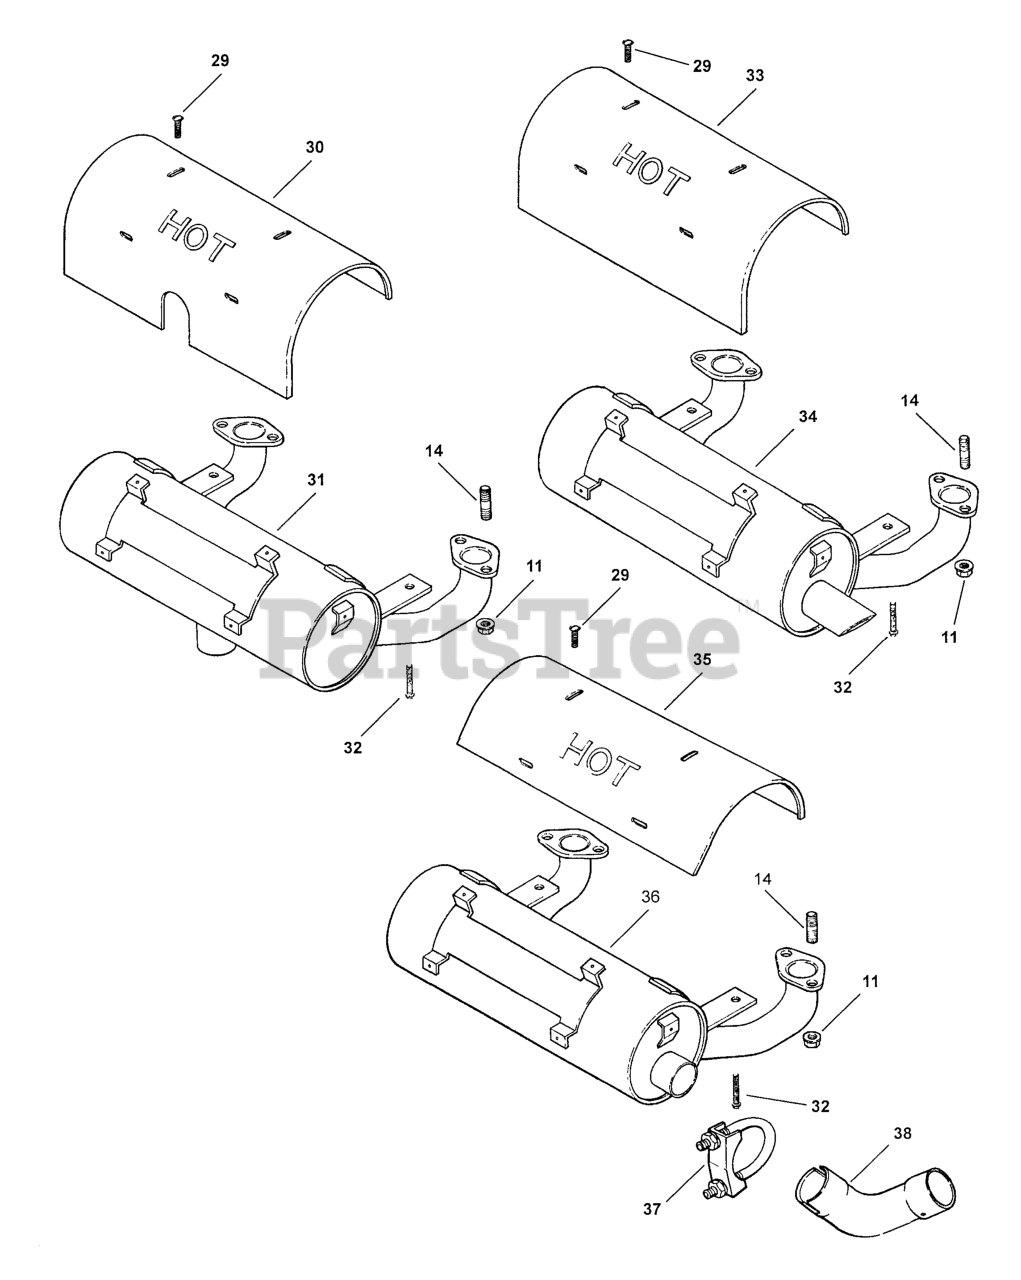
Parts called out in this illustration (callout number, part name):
11	Nut, Hex. Flange M8x1.25
14	Stud, Exhaust M8x1.25x20
29	Screw, Sems Drill 8-18x9/16"
32	Screw, Hex. Flange M6x1.0x20
33	Duct, Heat Shield
34	Muffler, Canister - Oil Filter Side Outlet
